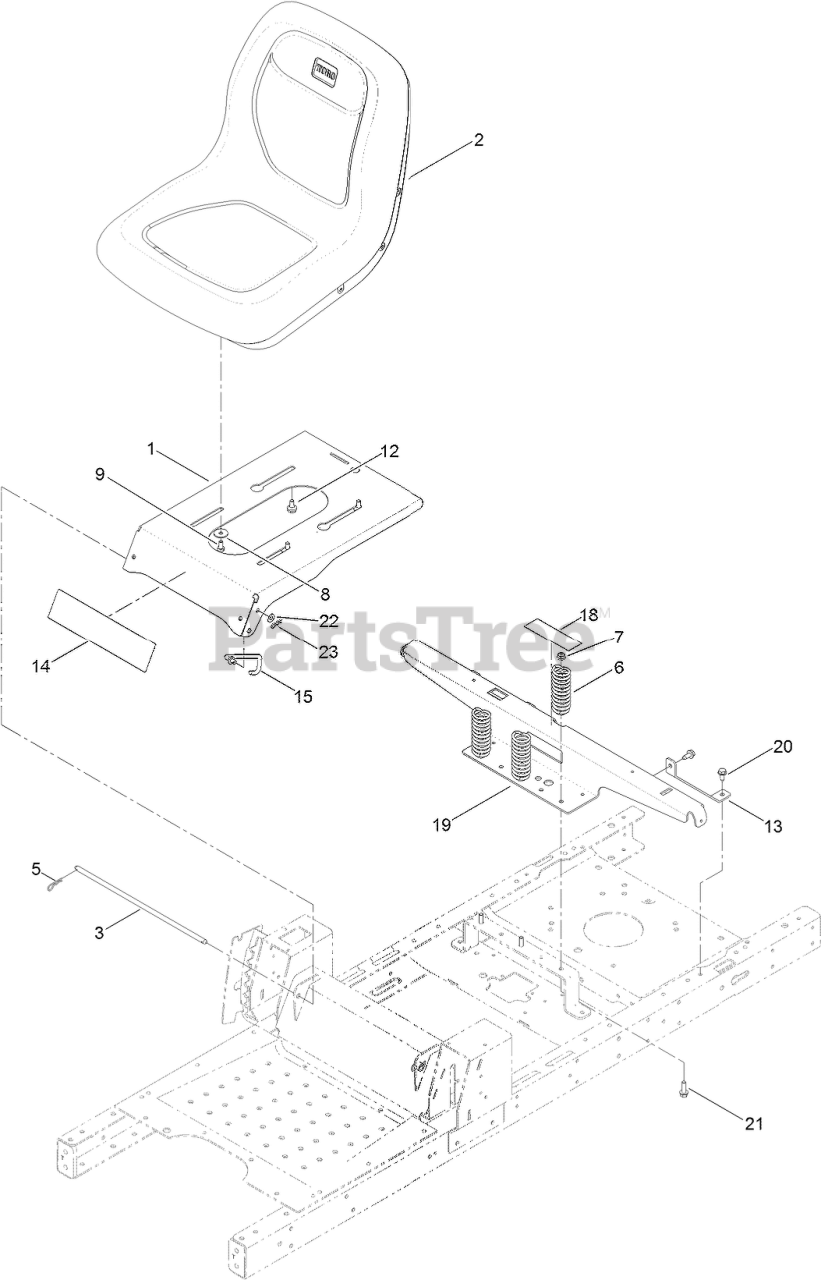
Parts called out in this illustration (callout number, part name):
1	PAN-SEAT
2	SEAT-18 INCH
3	ROD-PIVOT, NARROW
5	PIN-COTTER
6	SPRING-COMPRESSION
7	NUT-HF, NI
8	WASHER-PIVOT
9	SCREW-HH
12	BOLT-SHOULDER
13	SUPPORT-TANK, REAR
14	DECAL-TIMECUTTER
15	STOP-SEAT
18	DECAL-SERVICE, CE
19	SUPPORT-POD
20	SCREW-HWHTF
21	SCREW-HHF
22	WASHER-PLAIN
23	PIN-COTTER
